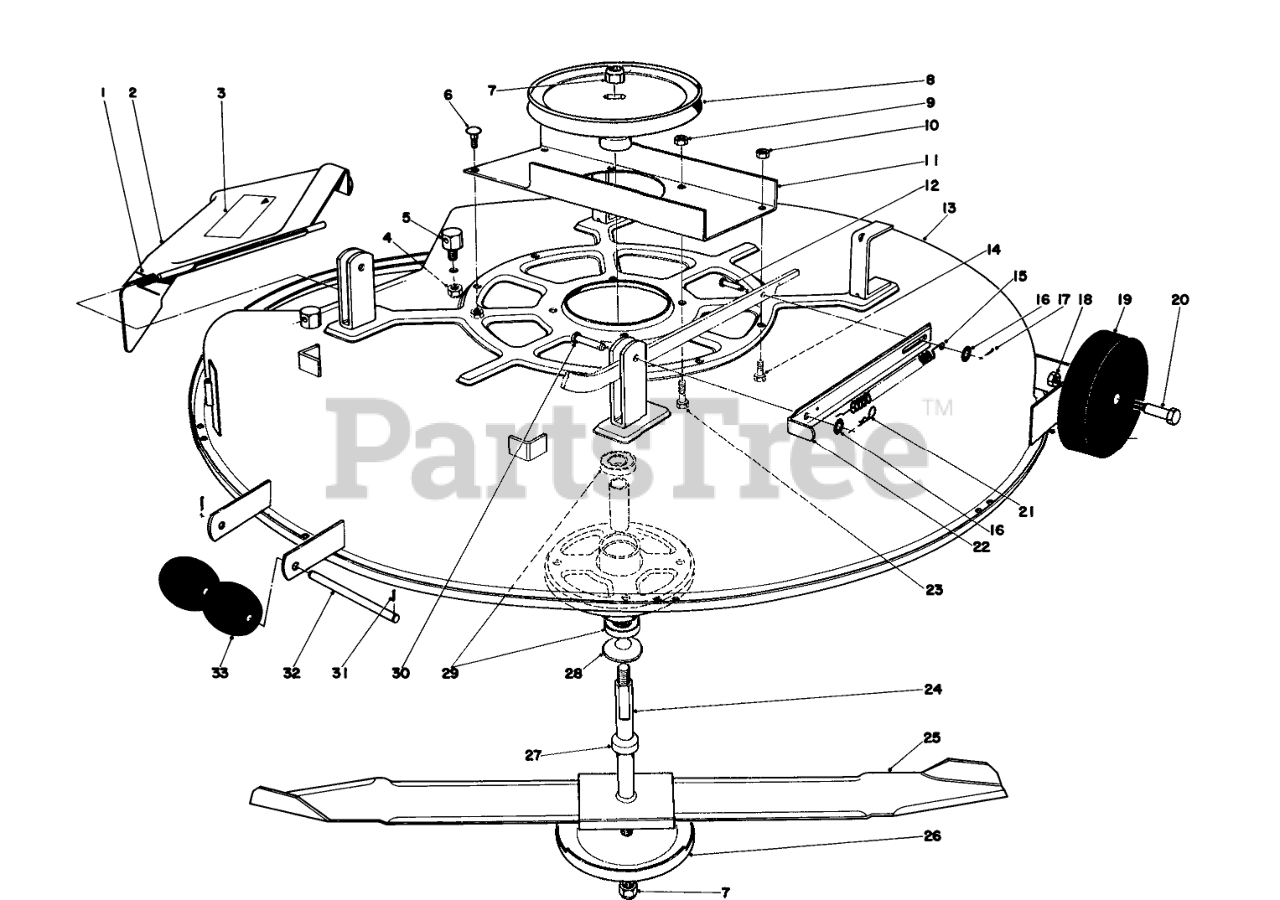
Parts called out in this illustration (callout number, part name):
1	SPRING
2	Deflector Assembly (Incl. Ref. #3)
3	Decal
4	NUT-LOCK, SIDE
5	POST-PIVOT
6	SCREW-CARR
8	PULLEY(BLADE DRIVE)
9	NUT-LOCK, CONE
11	REINFORCEMENT CHANNEL
12	PIN-CLEVIS
13	Cutter Deck
14	SCREW-HH
15	DECK TENSION SPRNG O
16	WASHER-FLAT
17	PIN-COTTER
18	Nut
19	DECK WHEEL
21	PIN-COTTER
22	DECK SPRING STRAP R
23	SCREW-HH
24	Spindle Assembly (Incl. Ref. #27-29)
25	Blade
26	Cup
27	SPACER
28	DUST COVER
29	BEARING
30	PIN-CLEVIS
31	PIN-COTTER
32	ROLLER SHAFT
33	ROLLER
